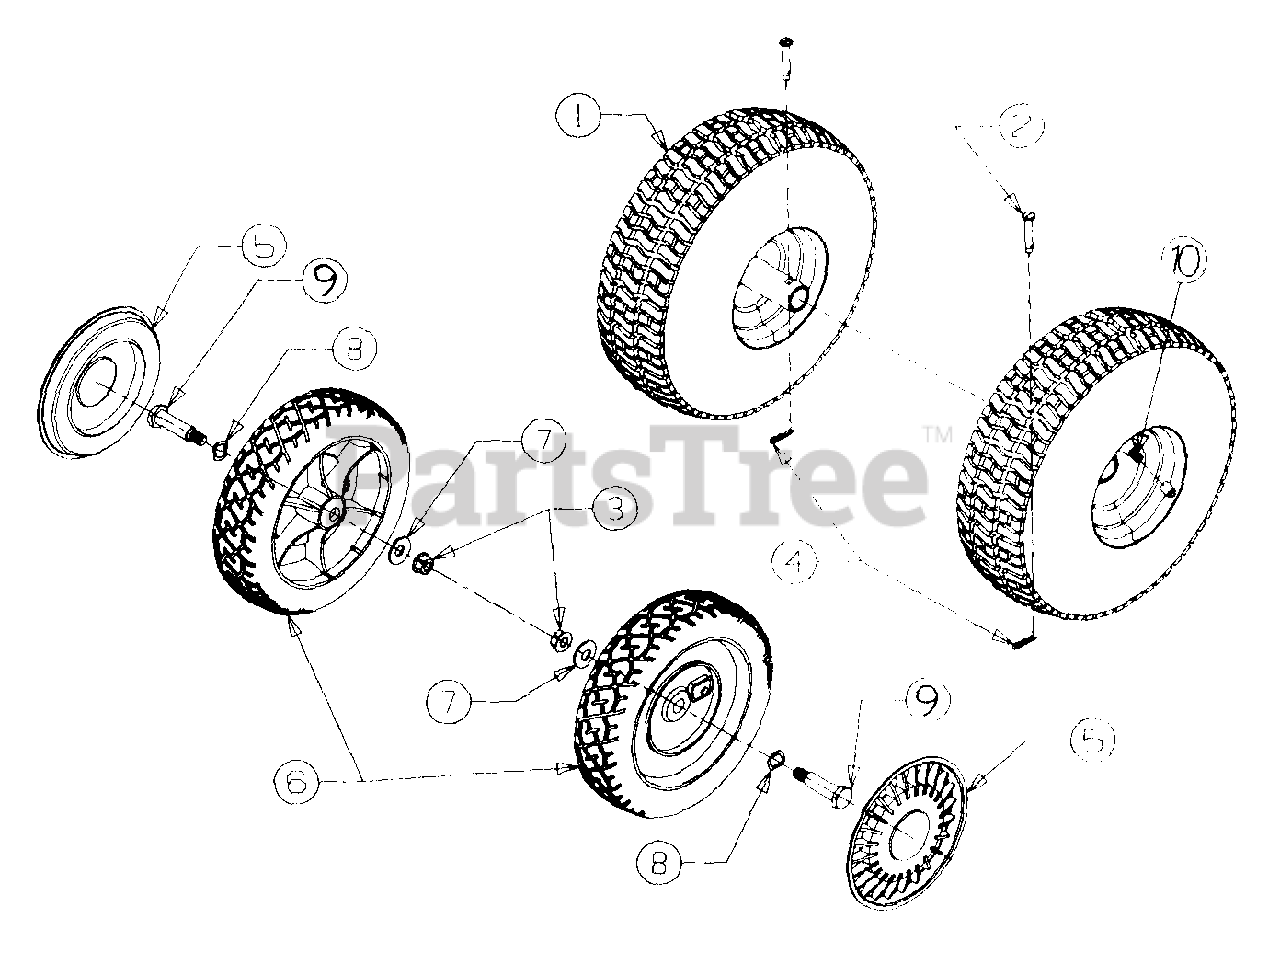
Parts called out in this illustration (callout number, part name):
1	WHEEL ASSY COMPLETE
2	PIN - CLEVIS
3	NUT - HEX FLANGE
4	PIN - COTTER
5	HUB CAP
6	WHEEL
7	WASHER - BELL
8	WASHER - WAVE
9	SCREW - SHOULDER
10	VALVE STEM
